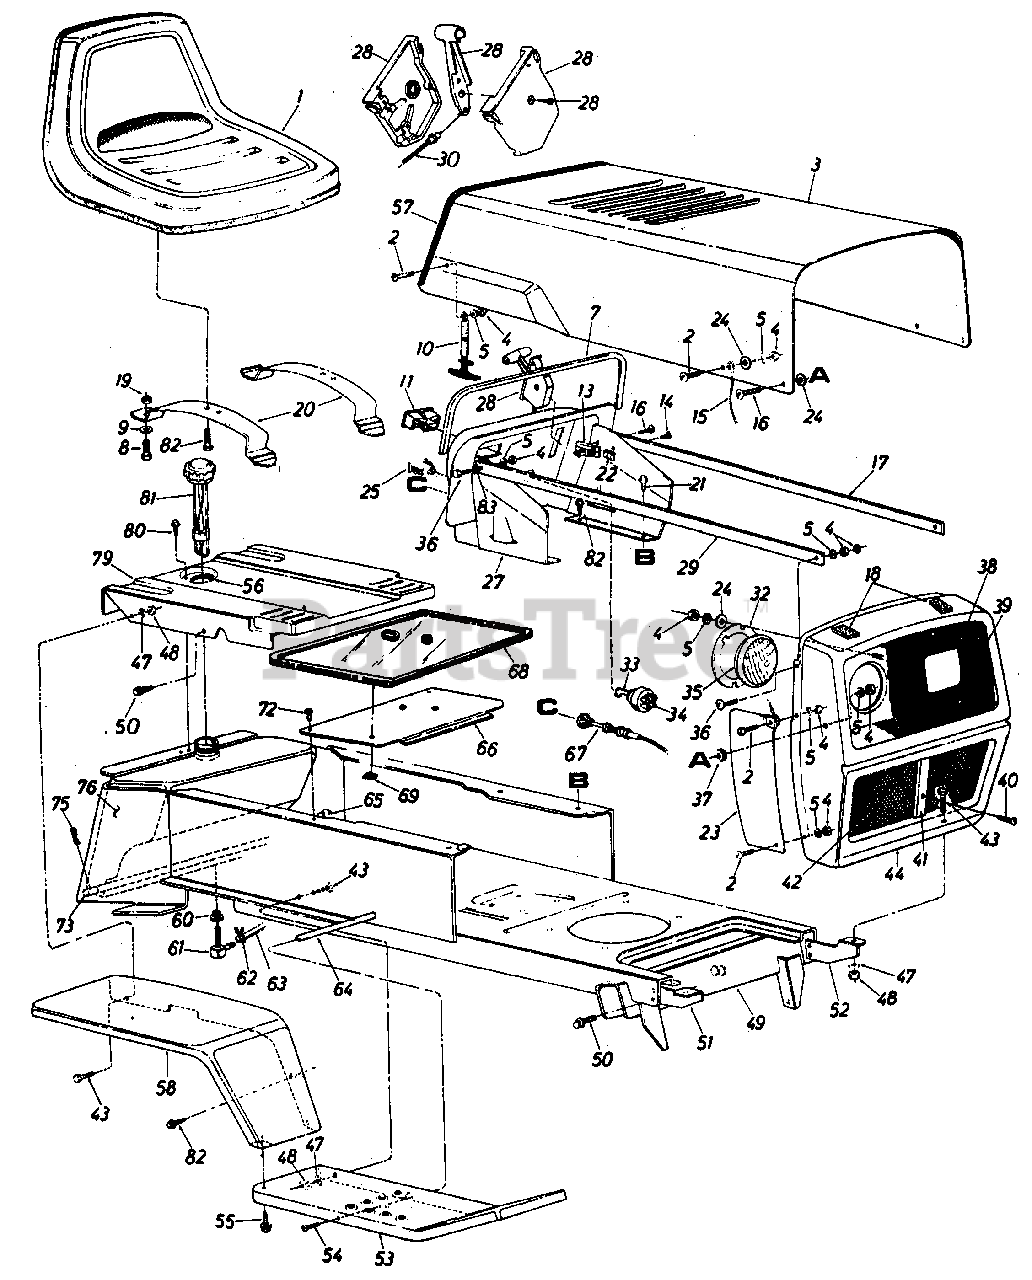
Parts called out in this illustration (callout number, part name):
1	Seat Assembly
2	Truss Mach. Scr. 1/4-20 x .50" Lg.*
5	L-Wash. 1/4" Scr.*
7	Vinyl Molding Strip 29"
8	Hex Nylon Scr. 1/2-13 x .75" Lg.
9	Fl-Wash. .50" I.D. x 1.00" O.D. x .090
10	Hood Latch Ass'y.
11	Ammeter
13	Circuit Breaker 8 Amp.
14	Hex Tap Scr. #10 x .50" Lg.*
15	Hood Stop
16	Truss Mach. Scr. 1/4-20 x .75" Lg.*
17	Grille Positioning Rod
18	PVC Foam Strip 1/2 x 1.00" x 2.00" Lg.
19	Hex Nut 1/2-13 Thd.*
20	Seat Spring
21	Hex Thd. Rolling Scr. 1/4" x .50" Lg.
22	Speed Nut #10Z
23	Grille Side Panel R.H.
23	Grille Side Panel L.H.
24	Fl-Wash. 1/4" I.D.
25	Light Switch
27	Dash Panel Ass'y.
28	Throttle Control Box Comp.
29	Grille Positioning Rod
30	Throttle Control Wire
32	Head Lamp Retainer
33	Ignition Key
34	Ignition Switch
35	Head Lamp
36	Truss Machine Scr. 1/4-20 x .75" Lg.
37	Rubber Wash. .50" I.D. x 1.00 O.D. x .25 Thk.
38	Headlight Bezel
39	Hex Wash. Hd. Scr. #8-32 x .38" Lg.
40	Truss Mach. Scr. #10-24 x .62" Lg.
41	Center Moulding
42	Grille Screen
43	Hex Scr. 5/16-18 x .75" Lg.*
44	Grille Ass'y.
47	L-Wash. 5/16" Scr.*
48	Hex Nut 5/16-18 Thd.*
49	Lower Frame Ass'y.
50	Hex Thd. Rolling AB Scr. 5/16 x .75" Lg.
51	Grille Mount Brkt. R.H.
52	Grille Mount Brkt. L.H.
53	Running Board R.H.
53	Running Board L.H.
54	Truss Mach. Scr. 5/16-18 x .75" Lg.*
55	Hex Thd. Rolling Scr. 5/16-24 x .75" Lg.
56	Grommet (Gas Tank Neck)
57	Vinyl Moulding Strip 30"
58	Fender Ass'y. R.H.
58	Fender Ass'y. L.H.
60	Bushing (Gas Tank)
61	90ø Nipple
62	Hose Clamp 3/8"
63	Gas Line 46" Lg.
64	Running Board Rod
65	Speed Nut
66	Transmission Cover
67	Choke Control Comp.
68	Transmission Cover
69	Speed Nut 1/4" Stud
72	Truss Hd. Scr. 1/4-20 x .75" Lg.
73	Hitch Rod
75	Internal Cotter Pin
76	Gas Tank
79	Seat Plate
80	Hex Thd. Rolling Scr. 5/16-24 x .75" Lg.
81	Gas Gauge
82	Hex Thd. Rolling Scr. 5/16-24 x .75" Lg.
83	External Wash. 1/4" I.D.
